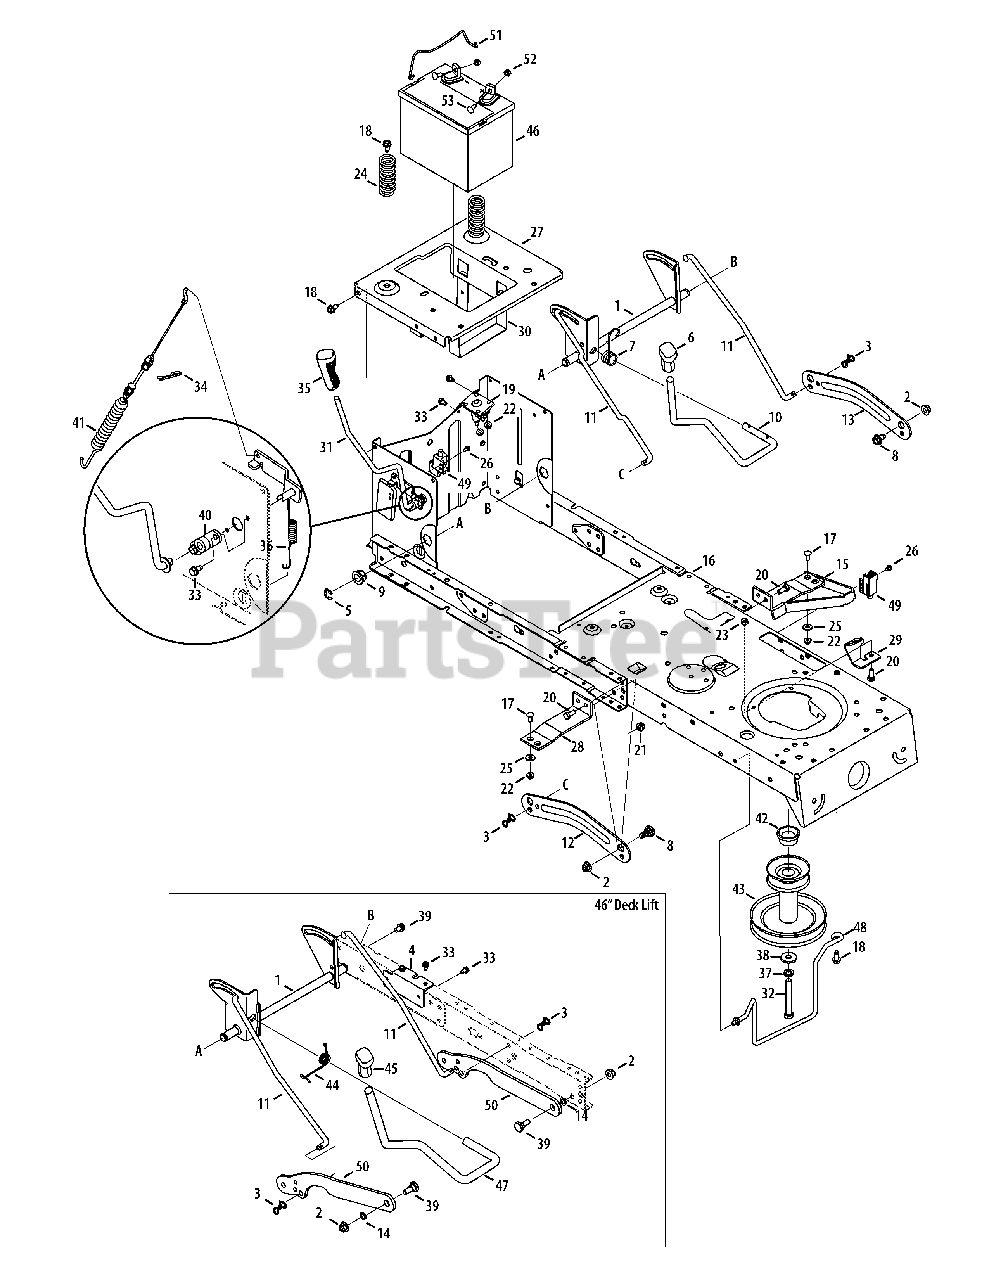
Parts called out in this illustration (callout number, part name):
1	Shaft Assembly Lift 42" Deck
1	Shaft Assembly Lift 46" Deck
2	Nut, Flange Lock, 3/8-16, GrF
3	Pin, Cotter, Bow Tie
4	Frame Brace Bracket
5	Ring, E-Type, .625 Dia.
6	Grip, Handle, 1/2
7	Spring, Torsion 42" Deck
8	Screw, Shoulder, .625 x .175
9	Bearing, Hex Flange
10	Deck Handle, Lift, 42" Deck
11	Rod, Lift
12	Lift Arm, Deck - RH
13	Lift Arm, Deck - LH
14	Washer, Flat, .385 x .62 x .063
15	Support Bracket Assembly
16	Frame Assembly
17	Carriage Screw, 1/4-20 x .62
18	Screw, 5/16-18, .750
19	Solenoid
20	Hex Screw, 5/16-18 x .75
21	Flange Lock Nut, 5/16-18
22	Nut, Flange Lock, 1/4-20, GrF
23	Hex Lock Nut, 5/16-18
24	Spring, Compr. , 1.28 OD x 3.125
25	Flat Washer, .28 x .74 x .063
26	Shoulder Screw, #10-32 x .500
27	Seat Bracket, Frame
28	Bracket, Runing Board
29	Frame Support Bracket
30	Bracket, Battery
31	Handle Assembly, PTO
32	Screw, 7/16-20, 3.25 42" Deck
33	Screw, 1/4-20, 0.500
34	Pin, Click, .092 x 1.64
35	Grip, Handle, 3/8
36	Spring, Extension
37	Washer, Lock, 7/16
38	Washer, Flat, .450 x 1.250 x .164
39	Bolt, Shldr. .500 x .270 3/8-16
40	Bearing, PTO
41	Cable, Deck Engagement
42	Spacer, 1.010 x 1.400 x .825, 42" Deck
43	Engine Pulley
44	Spring, Torsion 46" Deck
45	Grip, Handle
46	Battery, 155 CCA
47	Deck Handle, Lift, 46" Deck
48	Rod, Belt Keeper (42" Deck)
48	Rod, Belt Keeper (46" Deck)
49	Switch, Interlock
51	Battery Hold Down Rod
52	Nut, Sems, 1/4-20
53	Screw, Carriage, 1/4-20, .75, Gr5
